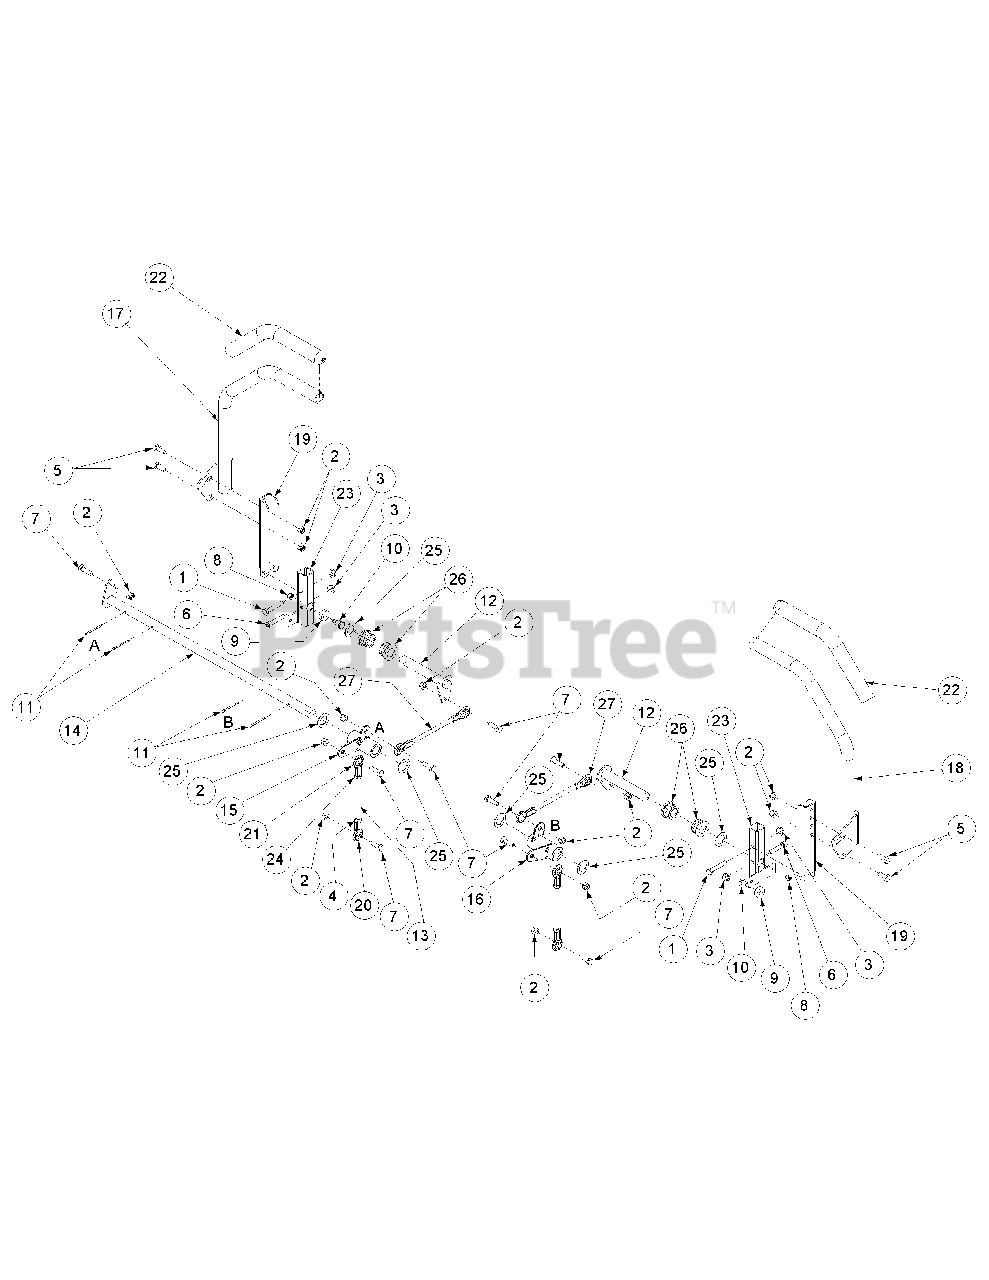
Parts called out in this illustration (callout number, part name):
1	Hex Cap Screw, 5/16-18 x 1-3/4
2	Nut, 5/16-18, Nylock
3	Nut, 5/16-18, Lock
4	Hex Nut, 5/16-24
5	Hex Cap Screw, 5/16-18 x 3/4
6	Capscrew, 5/16-18 x 1.50, Socket Head
7	Hex Cap Screw, 5/16-18 x 1.0
8	Nut, 1/4-28, SS, Nylon Insert
9	Control Rod Spacer
10	Shoulder Screw, 1/4-28
11	Cotter Pin, .125 Dia. x 1.0
12	Steering Input Shaft Assembly
13	Steering Link Rod
14	Bellcrank Steering Shaft Assembly
15	Steering Bellcrank Assembly Left Hand
16	Steering Bellcrank Assembly Right Hand
17	Steering Handle Assembly Left Hand
18	Steering Handle Assembly Right Hand
19	Steering Pivot Bracket
20	Rod End, 5/16, Right Hand
21	Rod End, 5/16, Left Hand
22	Lap Bar Grip
23	Pivot Bracket Weldment
24	Hex Nut, 5/16-24, Left Hand
25	Flat Washer, .793 ID x 1.24 OD x .060
26	Hex Flange Bearing, .752 ID
27	Control Rod Assembly
